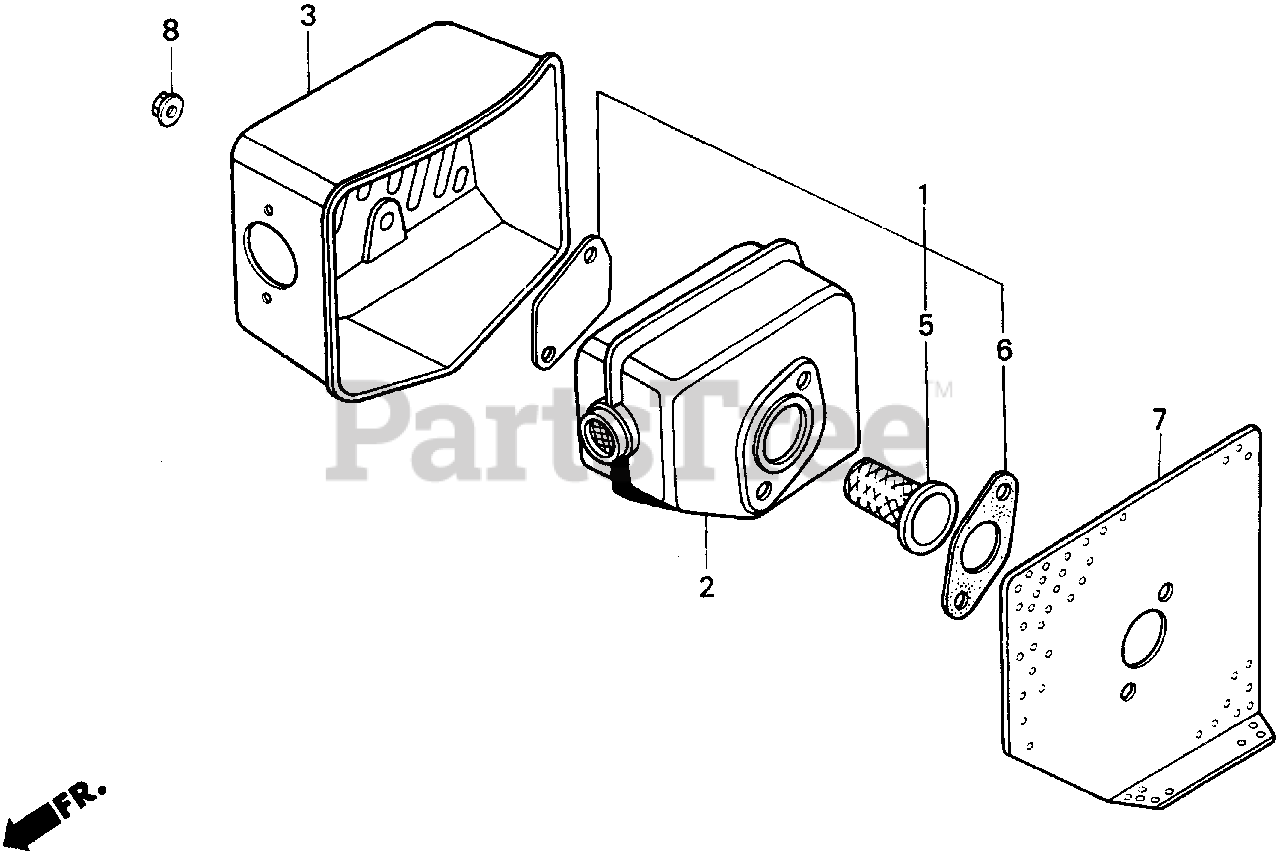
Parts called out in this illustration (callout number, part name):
1	ARRESTER KIT, SPARK
2	MUFFLER
3	PROTECTOR, MUFFLER
5	ARRESTER KIT, SPARK
6	GASKET, MUFFLER
7	GASKET, MUFFLER
8	NUT, SELF-LOCK (6MM)
